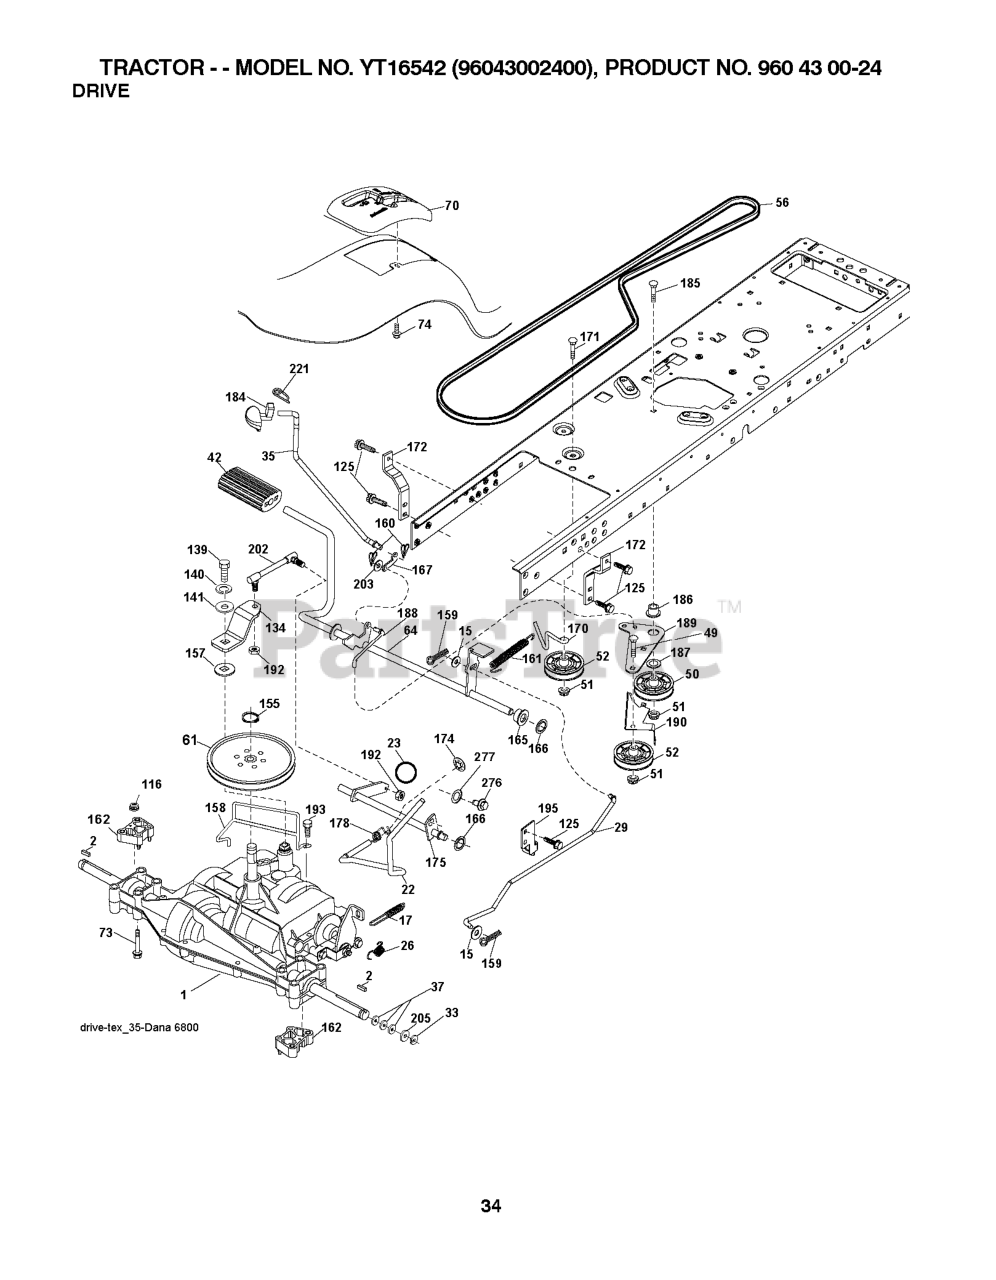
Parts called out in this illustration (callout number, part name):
2	SQUARE KEY
15	WASHER
17	SPRING.BRAKE.PEERLESS.TEX
22	ROD.SHIFT.FENDER.TLT.2006
23	KNOB T (1/2-HOLE)
26	SPRING.BRAKE.RTN.GR.DR
29	ROD.BRAKE.PEERLESS
35	ROD.CNTRL.PARK.PREDATOR.LT.TEX
42	PEDAL COVER T
50	IDLER.FLAT.910.OFFSET
51	NUT LOCK FLG 3/8-16 UNC
52	IDLER.V-GROOVE.910.OFFSET
56	V-BELT.TRACTOR.DRIVE.P
61	PULLEY TRANS
64	SHAFT.ASM.PEDAL.BRAKE.
70	CONSOLE.SHIFT.STL.6SP.GREY
73	BOLT HEX 5/16-18 GR 5
74	SCREW.HI-LO.CONSOLE
116	NUT LOCK HEX FLANGE 5/16-18
125	SCREW
134	ARM.SHIFT.
139	BOLT 1/4-28X3/4
140	LOCKWASHER
155	RETAINING RING LT
157	WASH-SHFT PLT LT
158	KEEPER.PMS.18/20.D4365
159	COTTER PIN
160	RETAINER CLIP
161	SPRING.RETURN.CLUTCH.2006
162	SPACER.TRANSAXLE.18&22
165	BUSHING.SHAFT.BRAKE.HAND
166	NUT.PUSH.625.2006
167	LATCH.BRAKE.SPRING
170	KEEPER.V-IDLER.CENTER.
172	STRAP.TRQ.LH.GEAR.DRIV
174	NUT.PUSH.500.2006
175	SHAFT.ASM.SHIFT.
178	SPRING.SHIFT.GT2006
184	HANDLE PARKING BRAKE
186	SPACER.RETAINER
187	WASHER 12/32X2X10GA
188	RP.LINK.CLUTCH.GROUND.DRIVE
189	BELLCRANK.GROUND.DRIVE.TEX.
190	KEEPER.BELLCRANK.DRIVE
192	NUT LOCK CENTER 1/4 -28 FNTHD
193	SCREW 5/16"
195	BRKT.ROD.BRAKE.PEERLES
202	LINK.TRANSAXLE.D6800.18/20"TEX
203	WASHER
221	RETAINER.SPRING.CLIP.H
276	BOLT FIN HEX 7/16-14 X 1
277	WASHER SERRATED
